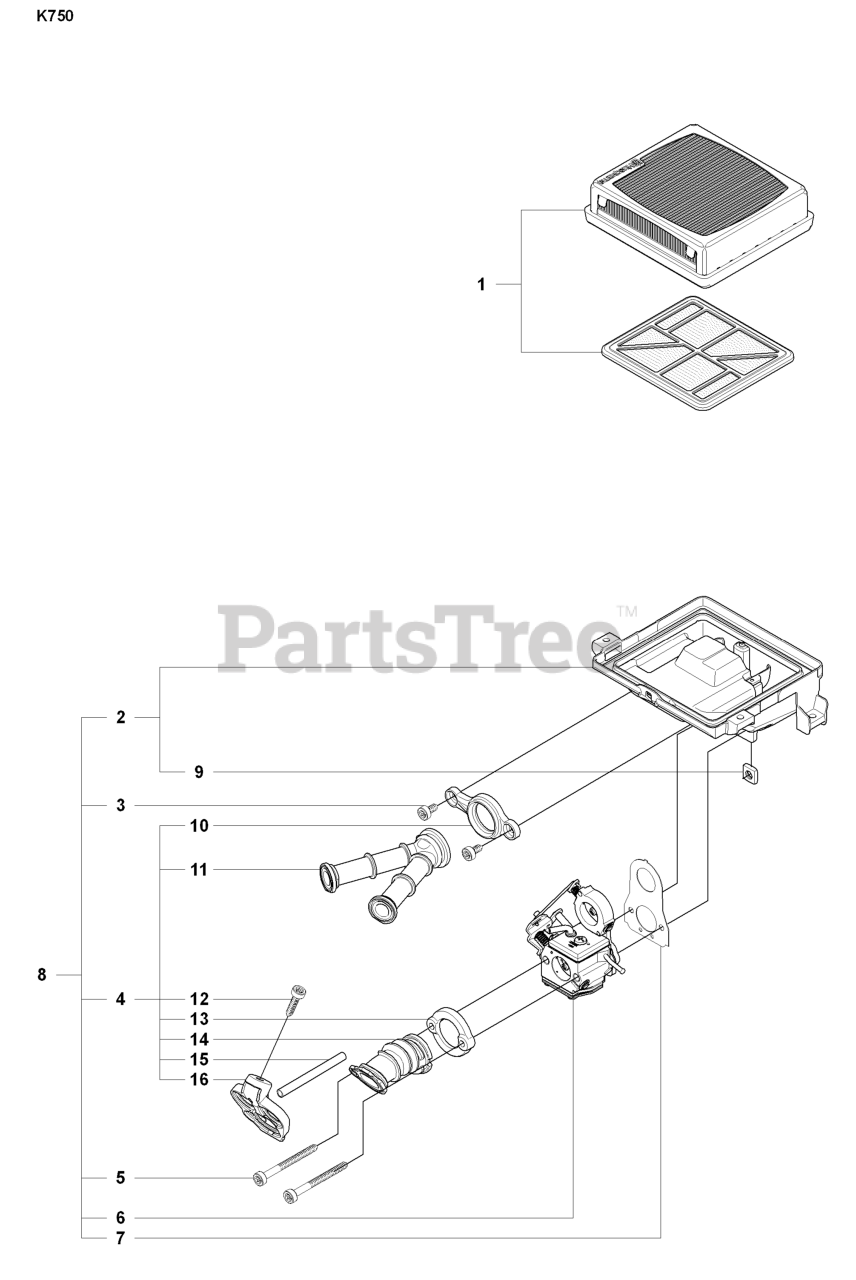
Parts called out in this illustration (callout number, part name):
2	CARBRETOR BRACKET
4	INLET PIPE ASSY WITH INSERT
6	CARBURETOR
7	RP CARBURETOR GASKET
8	CARBURETTOR BRACKET
11	RP INLET PIPE
13	FLANGE
14	RP INLET PIPE
15	RP HOSE
16	%PLATE
